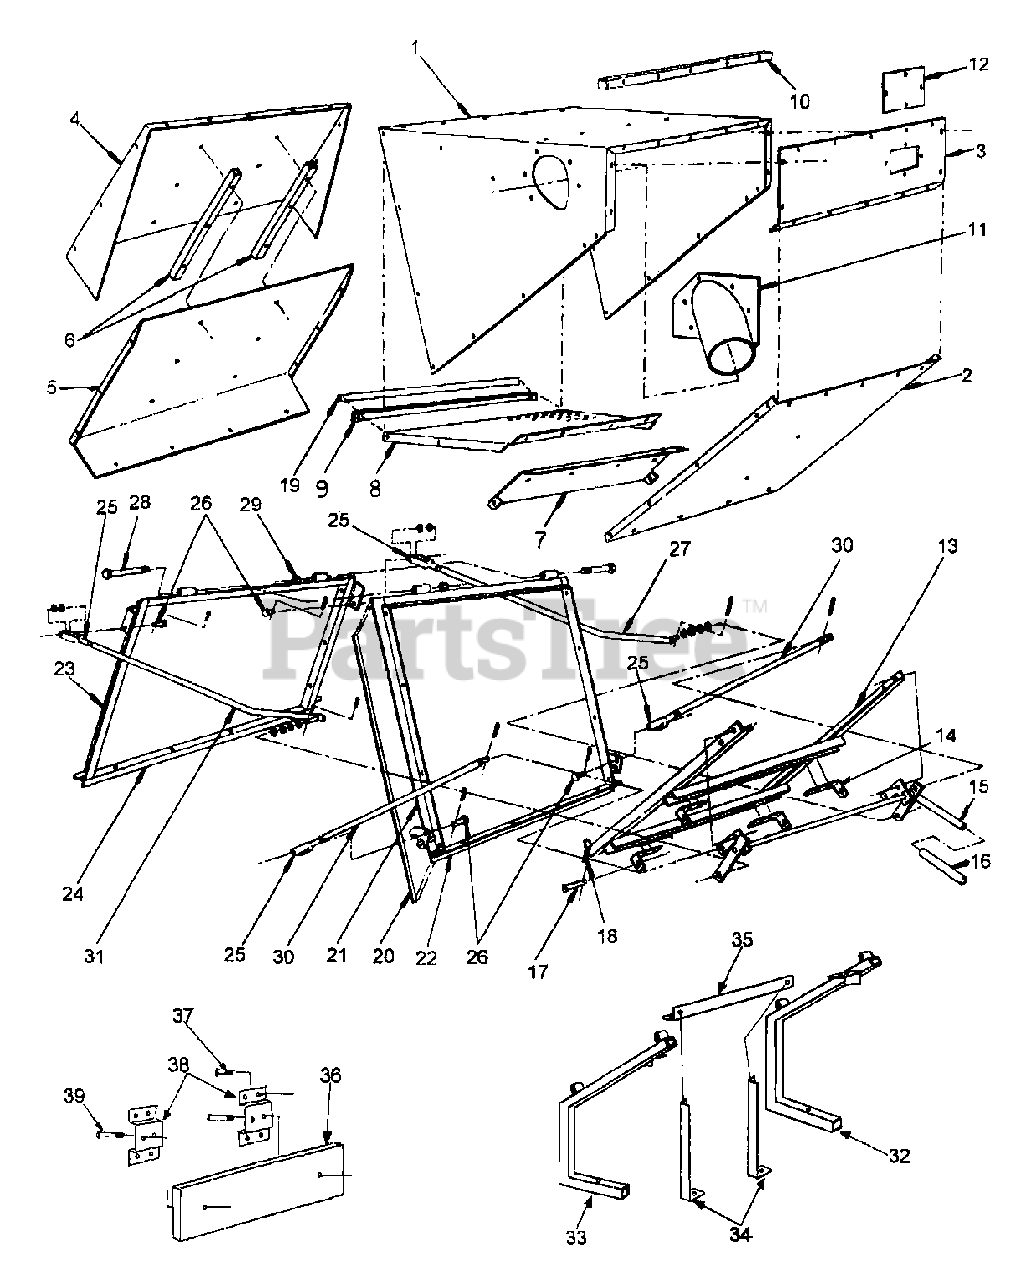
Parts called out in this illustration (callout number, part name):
1	Catcher Body
2	Catcher Box Bottom
3	Catcher Front
4	Outer Door Shell
5	Inner Door Shell
6	Door Vent Spacer
7	Intake Deflector
9	Rear Screen Support
10	Front Bumper
11	Intake Tube 6"
12	Viewing Window
13	Catcher Frame Base
14	Base Frame Tab
15	Lever Dump Assembly
16	Vinyl Grip 5"
17	Clevis Pin 1/2" x 3"
18	Hair Spring Cotter # 6
19	Rubber Seal
21	Catcher Frame Opening
22	Bottom Catcher Frame Opening
23	Catcher Door Frame
24	Bottom Door Frame
25	Adjustable Yoke End 3/8"-24
26	Clevis Pin 3/8" x 1-1/8"
27	Hinge Rod Left
31	Hinge Rod Right
32	Catcher Mounting Left
33	Catcher Mounting Right
34	Catcher Mounting Support
36	Weight Bar
38	Weight Mounting Bracket
